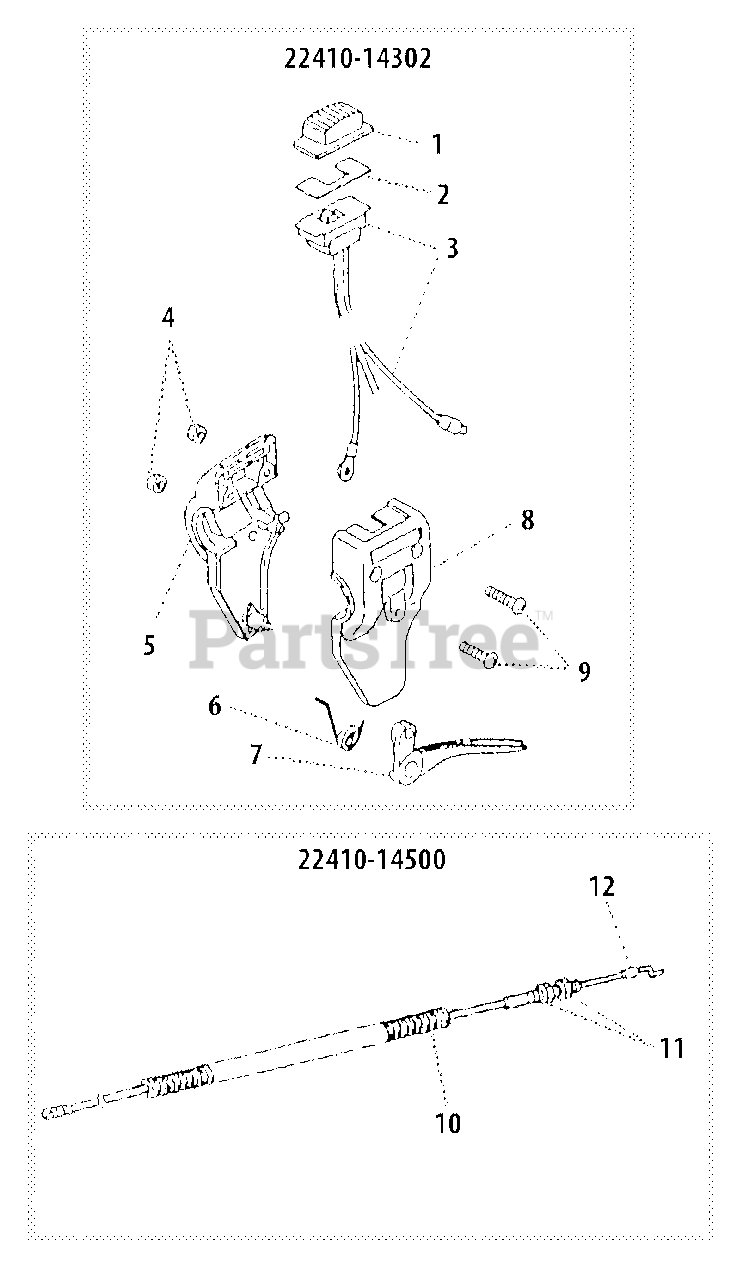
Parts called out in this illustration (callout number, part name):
1	KNOB, SWITCH
2	PLATE, SWITCH
3	SWITCH
4	NUT M5
5	CONTROL HANDLE - RIGHT
6	SPRING, RETURN
7	TRIGGER, THROTTLE
8	CONTROL HANDLE - LEFT
9	SCREW
10	TUBE, PLASTIC PROTECTIVE
11	NUT M6
12	CABLE, THROTTLE
22410-14302	THROTTLE CONTROL KIT
22410-14500	THROTTLE CABLE ASSY
